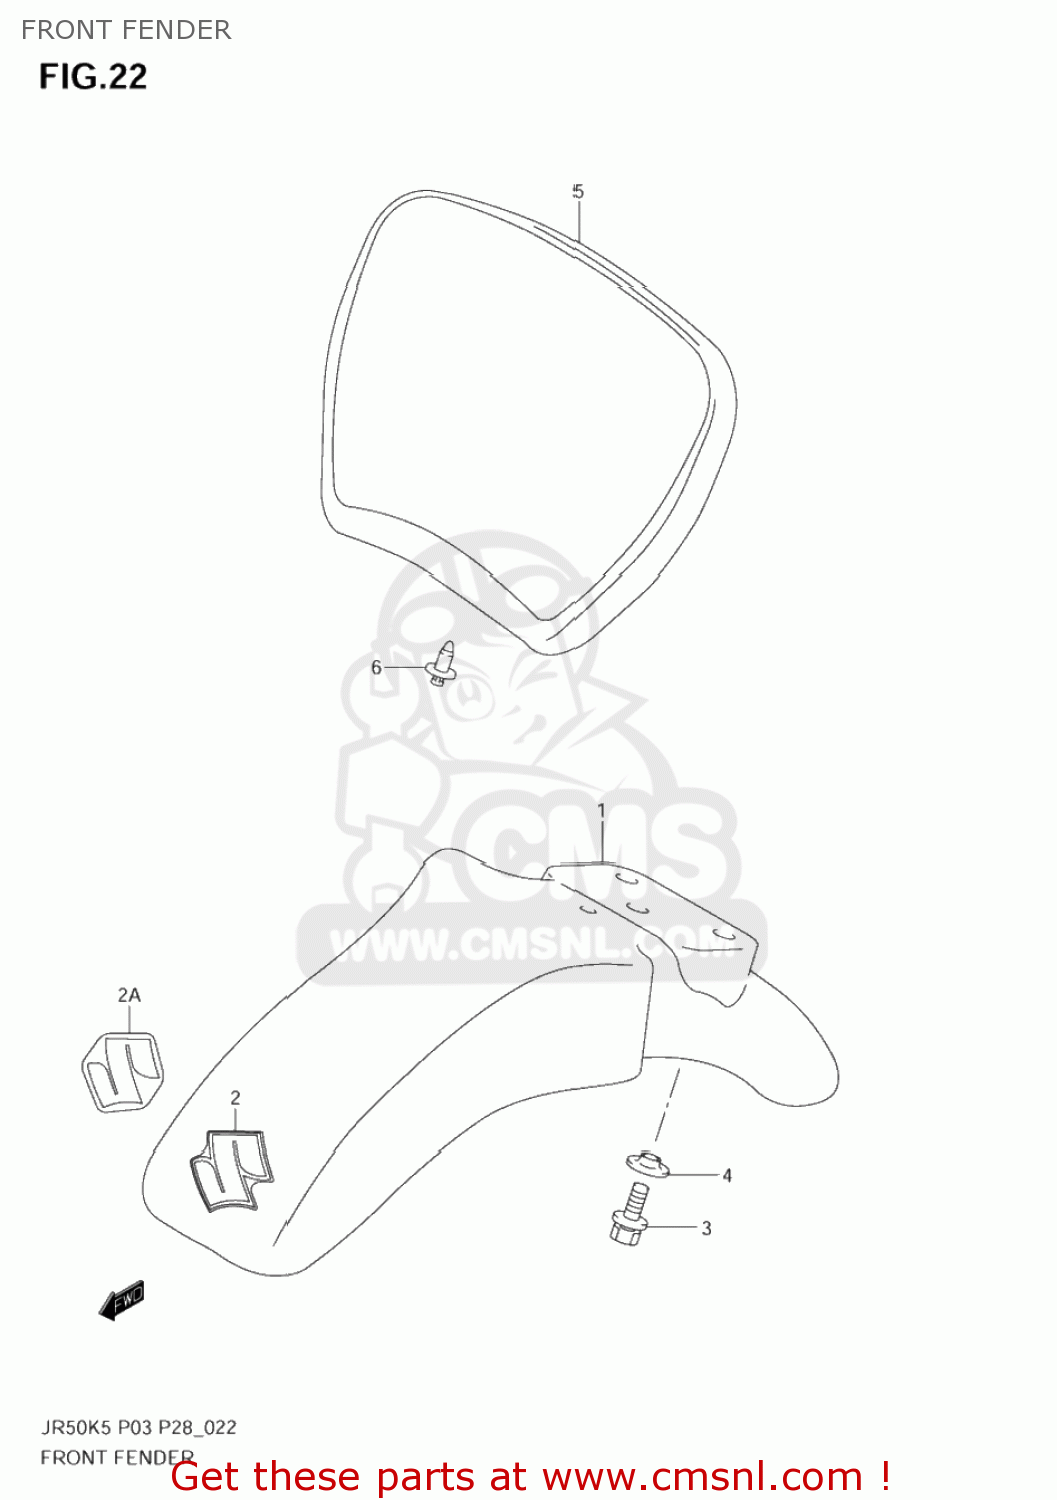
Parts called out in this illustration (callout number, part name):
1	FENDER,FR
2	EMBLEM,S
2A	EMBLEM,S
3	BOLT(6X16)
4	WASHER
5	PLATE,NUMBER FR
6	CLIP(BLACK)
